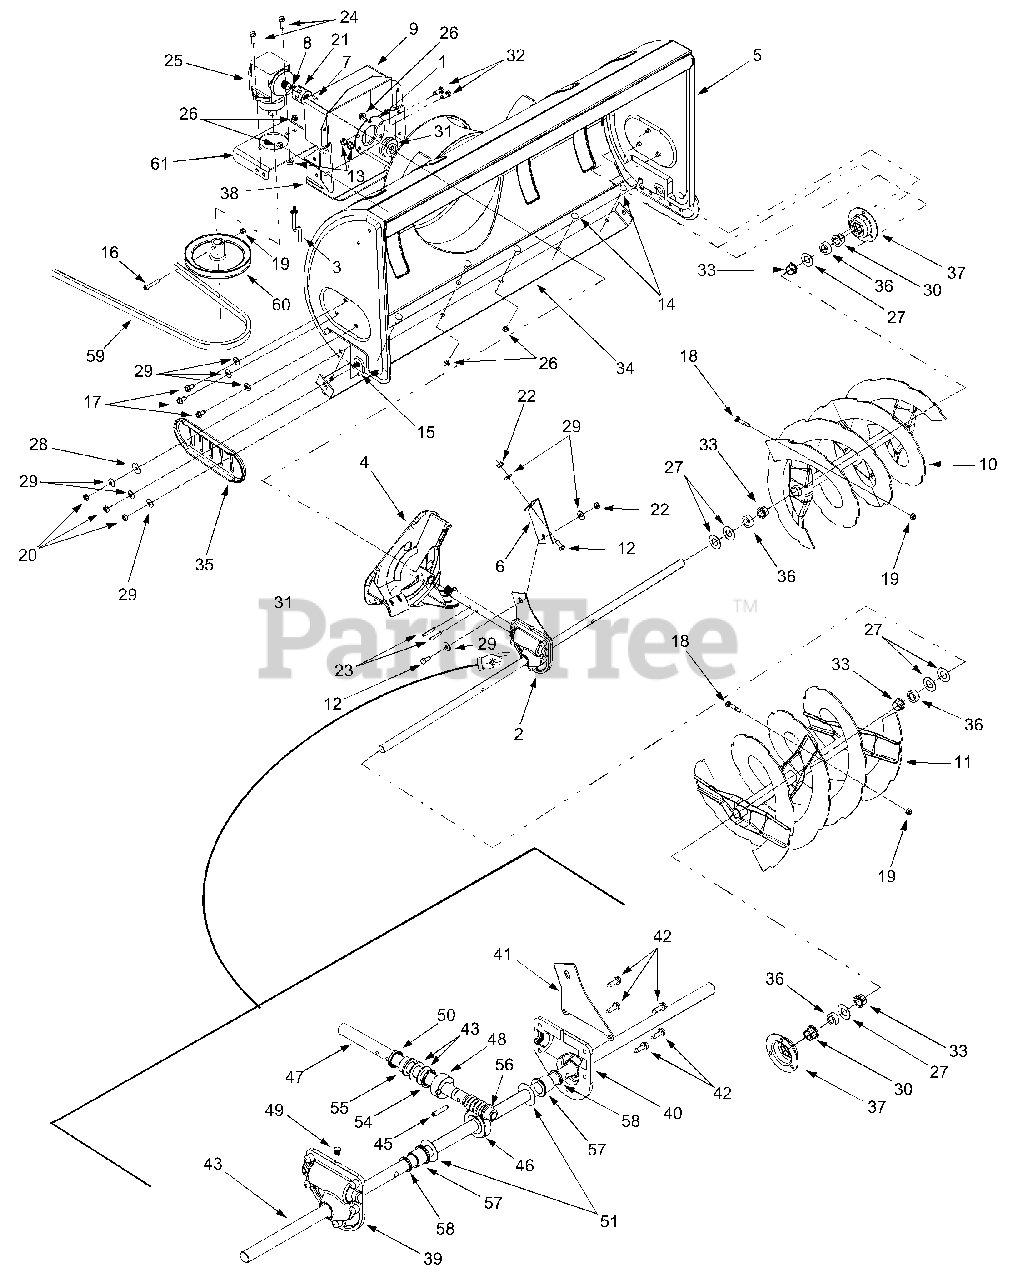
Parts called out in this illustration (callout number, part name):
1	Bearing Housing, 1.85 ID
2	Auger Gear Case
3	Belt Keeper Rod
7	Square Key, 3/16 x .75
8	Hi-pro Key, 3/16 x .75
13	Flange Lock Nut, 3/8-16
14	Carriage Bolt, 5/16-18 x .62
15	Splined Carriage Screw, 5/16-18 x
16	Socket Head Cap Screw, 5/16-18
17	Self Tapping Screw, 5/16-18 x .625
18	Shear Bolt, 5/16-18 x 1.5
19	Hex Lock Nut, 5/16-18
20	Hex Nut, 5/16-18
21	Coupling
22	Hex Nut, 5/16-24
23	Spirol Pin, 1/4 x 1-1/2
24	Hex Cap Screw, 3/8-16 x 1.0
25	Right Angle Drive
26	Flange Lock Nut, 5/16-18
27	Flat Washer, .76 x 1.49 x .06
28	Flat Washer, .344 x 1.125 x .12
29	Bell Washer, .340 x .872
30	Hex Flange Bearing, .75 ID
31	Flange Ball Bearing, .75 x 1.85
32	Hex Cap Screw, 3/8-16 x .75
33	Flange Bushing, .80 x .91
36	Spacer, .75 x .125 x .5
39	RH Reducer Housing
40	LH Reducer Housing
42	Self Tapping Screw, 1/4-20 x .75
43	Spiral Axle, 41.5"
45	Spring Spiral Pin, .25 x 1.25
46	Worm Gear, 20-tooth
47	Worm Shaft
48	Thrust Collar
49	Grease Plug
50	Grease Seal
51	Flat Washer, .76 x 1.5 x .030
54	Thrust Bearing, .75 x 1.25 x .078
55	Flange Bearing, .75 x 1.0 x .59
56	Flange Bearing, .503 x .75
57	Flange Bearing, .754 x 1.0 x .925
58	Grease Seal
59	Lower V-belt
60	Drive Pulley, 7"
